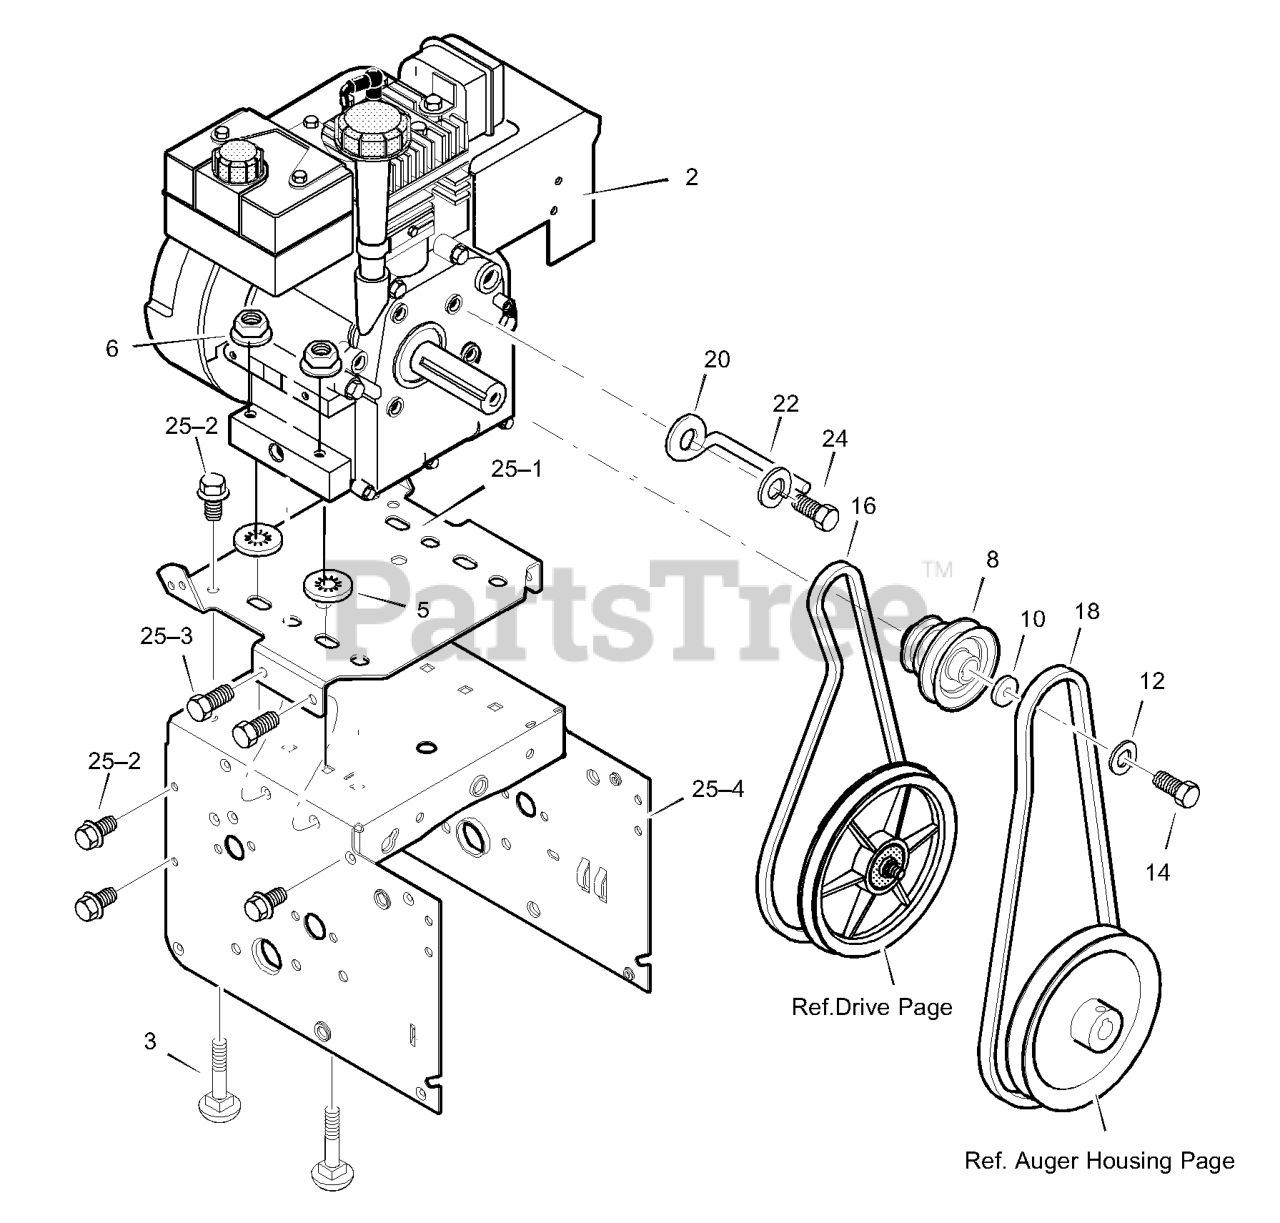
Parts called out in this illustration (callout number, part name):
2	ENGINE
3	BOLT, CARRIAGE 5/16-18
5	RETAINER, PUSH
6	NUT, HEX 5/16-18
8	PULLEY, ENGINE
10	WASHER
12	WASHER .38ID
14	SCREW, 3/8-24 x 1.00
16	BELT, V 3L 33.13LG
18	BELT, V 4L 38.1MF16" 5-10
20	GUIDE, BELT
22	WASHER, SPTLK .31 X .58X.08
24	SCREW, 5/16-24 x 0.75
25	FRAME ASSEMBLY
25-1	PLATE, ENGINE MOUNT
25-2	SCREW, TAP 1/4-20 X .63
25-3	SCREW, TAP 5/16-18 X .50
25-4	FRAME, MOTOR BOX
